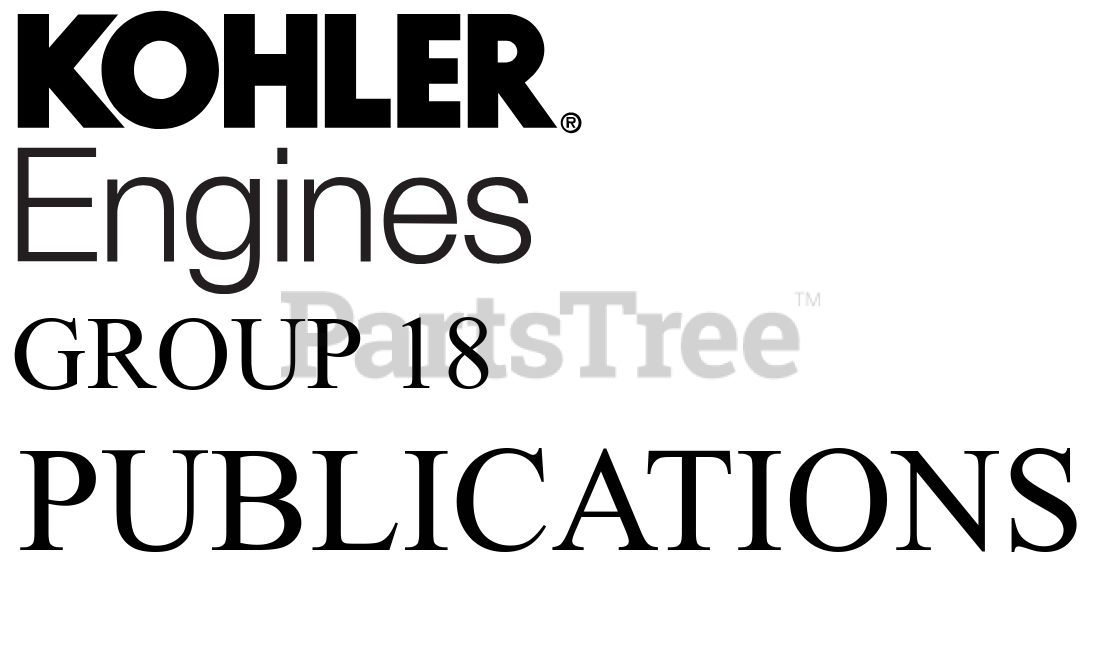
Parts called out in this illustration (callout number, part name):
NI	OM, ZT710-ZT740 AMERICAS
NI	SM, ZT710-ZT740 ENGLISH
NI	SM, ZT710-ZT740 FRENCH CANADIAN
NI	SM, ZT710-ZT740 GERMAN
NI	SM, ZT710-ZT740 ITALIAN
NI	SM, ZT710-ZT740 SPANISH
NI	SM, ZT710-ZT740 CHINESE
NI	WARRANTY, COMBINED 2020-2022 MY
